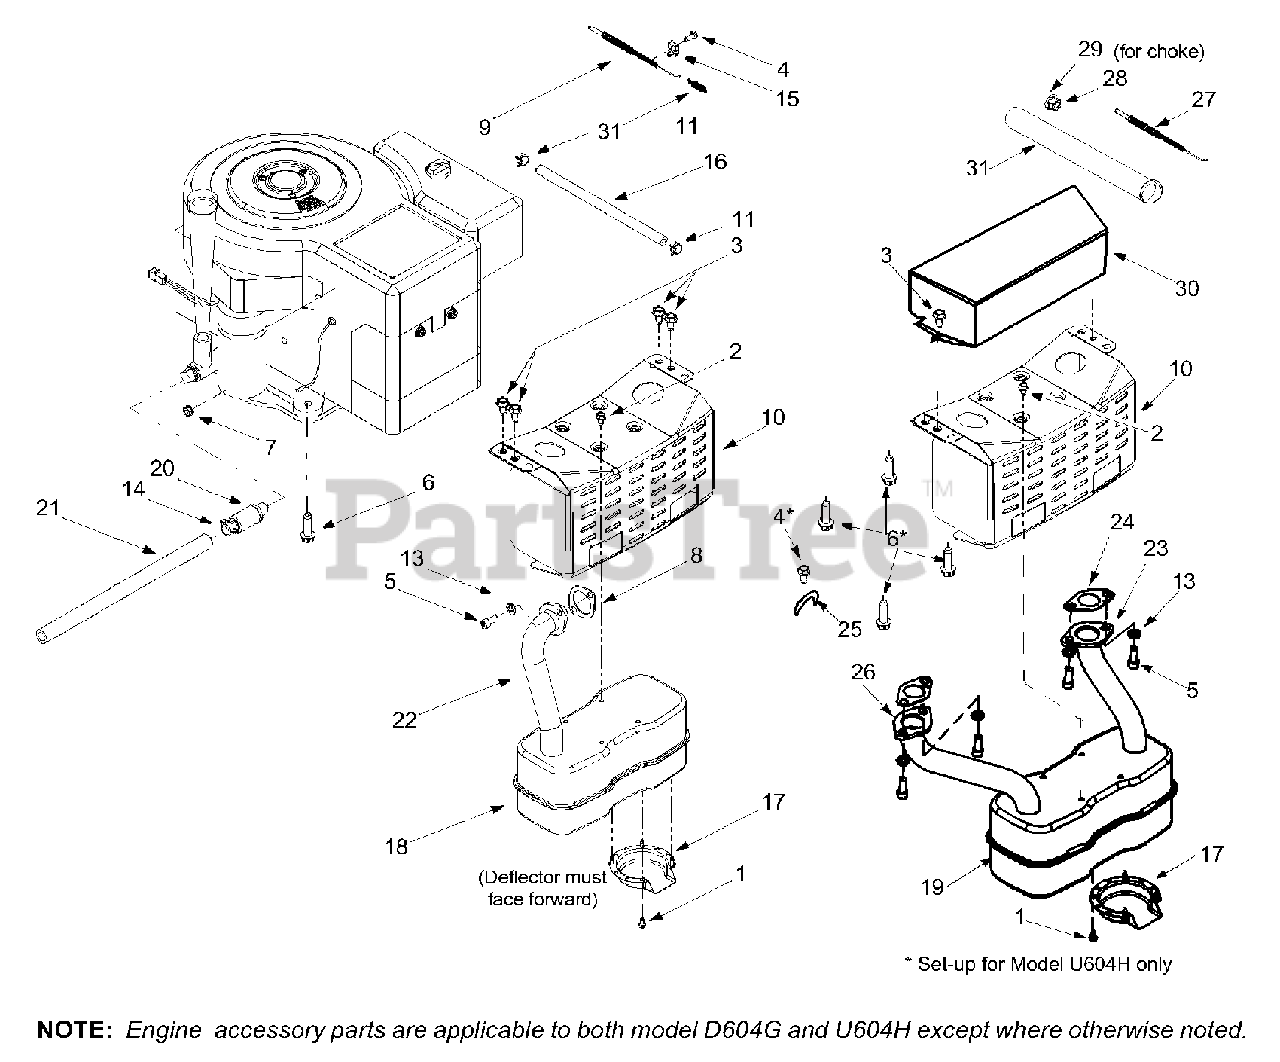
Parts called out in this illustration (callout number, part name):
1	Self-tapping Screw, #8-18 x .5
2	Self-tapping Screw, 1/4-20 x .5
3	Self-tapping Screw, 5/16-18 x .625
4	Screw, #10-32 x .625 (Model D604G)
5	Socket Cap Screw, (Model D604G)
6	Self-tapping Screw (Model D604G)
7	Sems Nut, 1/4-20 (Model D604G)
8	Exhaust Gasket (Model D604G)
9	Throttle Cable (Model D604G)
11	Hose Clamp
13	Lock Washer, 5/16 (Model D604G)
14	Oil Drain Cap
15	Casing Clamp (Model D604G)
16	Fuel Line Hose
17	Muffler Deflector
18	Muffler
19	Muffler (Model U604H)
20	Oil Drain Valve
21	Oil Drain Hose
22	Exhaust Pipe (Model D604G)
23	Exhaust Pipe LH (Model U604H)
24	Exhaust Gasket (Model U604H)
25	Casing Clamp (Model U604H)
26	Exhaust Pipe RH (Model U604H)
27	Throttle Cable (Model U604H)
28	Hex Nut, 3/8-16 (Model U604H)
29	Flat Washer (Model U604H)
30	Heat Shield (Model U604H)
31	Foam Cover: Fuel Line (Model U604H)
